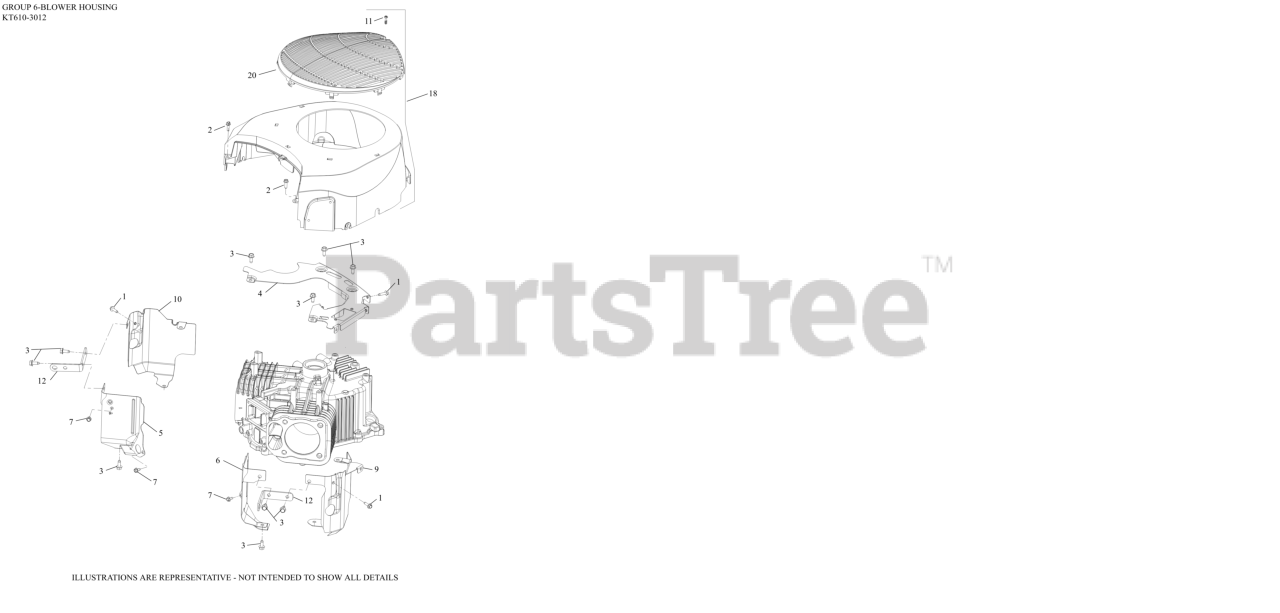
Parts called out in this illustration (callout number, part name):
1	SCREW, THD FRM-USE 25 086 473-S
2	SCREW, HI-LOW
3	SCREW, THREAD FORMING
4	PLATE, BACKING
5	BAFFLE, VALLEY #1
6	BAFFLE, VALLEY #2
7	SCREW, THREAD FORMING
9	BAFFLE, LEFT BARREL
10	BAFFLE, RIGHT BARREL
11	SCREW, M5-2.42 (PT) THREAD
12	STRAP, LIFTING
18	KIT, BLOWER HOUSING
20	GUARD, FIXED
